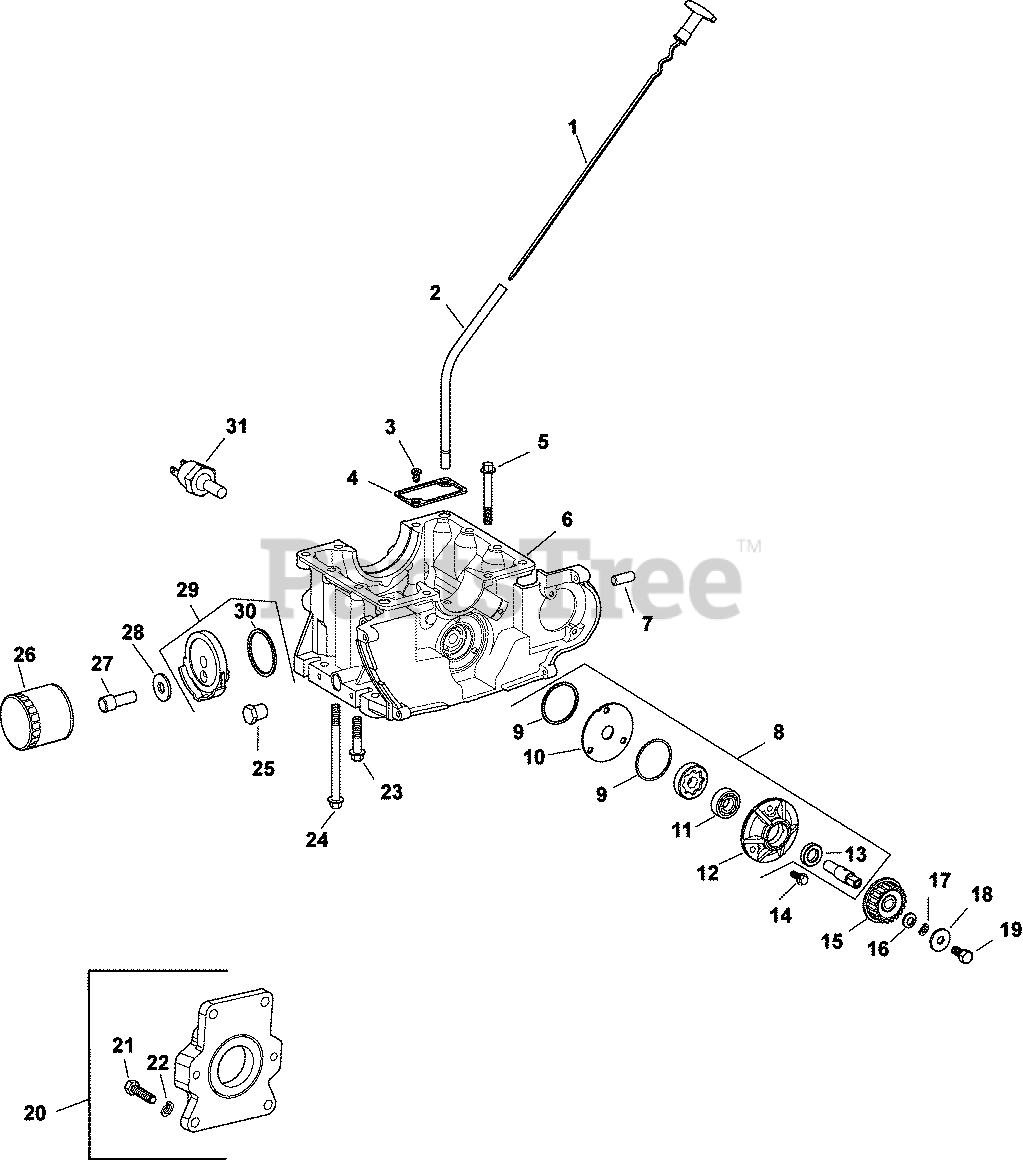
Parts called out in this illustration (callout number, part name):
1	DIPSTICK - DISCONTINUED
2	TUBE, DIPSTICK - DISCONTINUED
3	SCREW, TORX COUNTRSUNK HD
4	SCREEN, OIL PICK-UP - (#DSC)
5	SCREW, FLG M8X1.25X70
6	CRANKCASE
7	VALVE, PISTON RELIEF
8	PUMP ASSEMBLY, OIL - DISC.
9	O-RING - DISCONTINUED
10	PLATE, WEAR - DISCONTINUED
11	BEARING, BALL
12	COVER, OIL PUMP - DISCONTINUED
13	SEAL, OIL - DISCONTINUED
14	SCREW, FLG M6x1.0x20
15	SPROCKET, OIL PUMP - (#DSC)
16	WASHER, SPRING 13 MM
17	WASHER, SPRING LOCK 1/4"
18	WASHER, FLAT 1/4"
19	SCREW, HEX HEAD MACHINE
20	KIT, PUMP ADAPTER
21	SCREW,CAP HD 7/16-14x1 1/2"
22	WASHER, SPRING LOCK 7/16"
23	SCREW, FLG M8X1.25X40 - (#M851040S)
24	SCREW, FLG M8X1.25X115
25	PLUG, HD PIPE 3/8"
26	OIL FILTER
27	NIPPLE, OIL FILTER
28	WASHER, FLAT - DISCONTINUED
29	KIT, PLASTIC FILTER ADAPTER - DISCONTINUED
30	O-RING - DISCONTINUED
31	KIT, OIL SENTRY(PRESSURE) - (#DSC)
